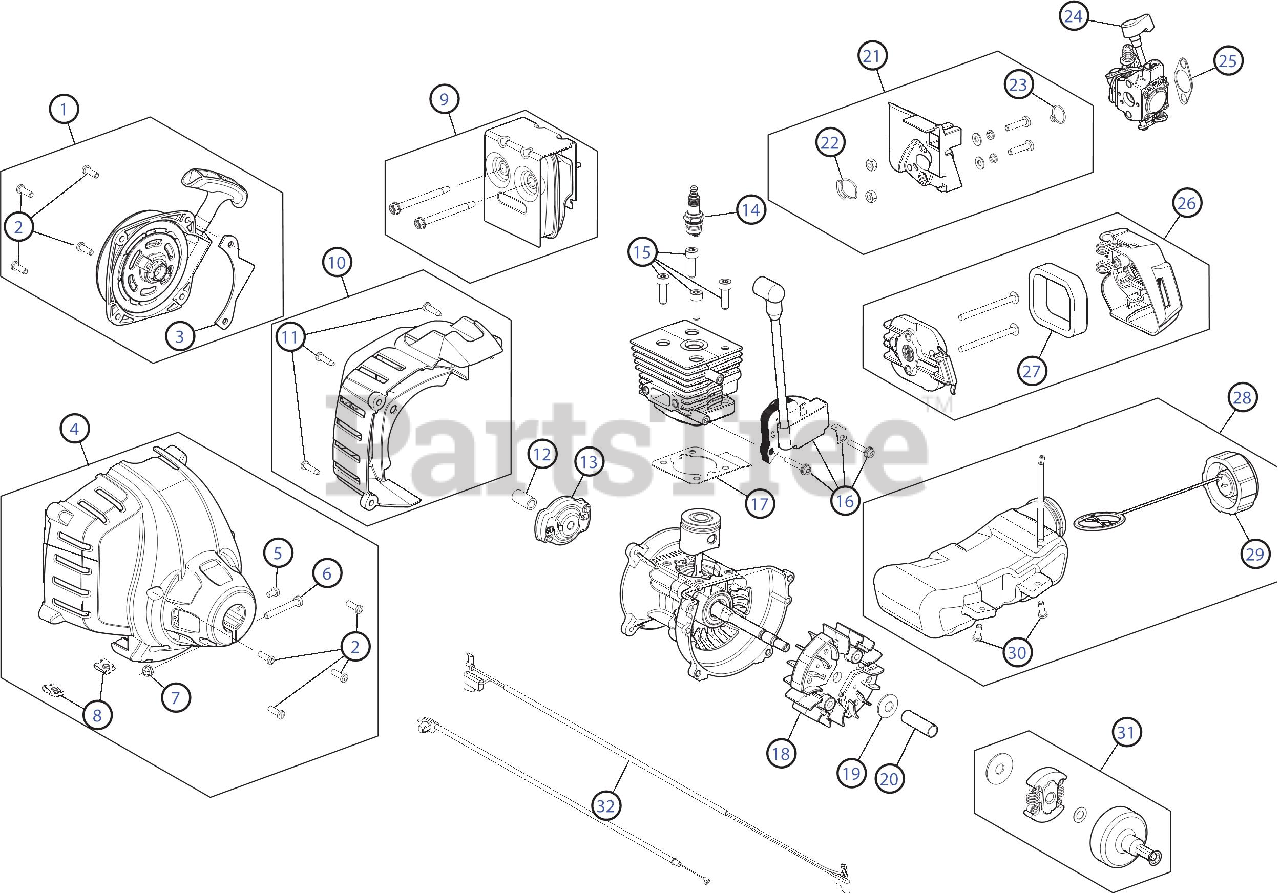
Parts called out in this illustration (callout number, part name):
1	Starter Assembly
2	Starter Screw
3	Starter Assembly Guard
4	Clutch Cover Assembly
5	Anti-Rotation Screw
6	Clamp Screw
7	Clamp Nut
8	U-shaped Nut
9	Muffler Assembly
10	Rear Engine Cover
11	Cover Screw
12	Adapter
13	Pawl Assembly
14	Spark Plug
15	Cylinder Bolt
16	Module Assembly
17	Cylinder Gasket
18	Flywheel Assembly
19	Washer
20	Spacer
21	Insulator Assembly
22	Insulator O-Ring
23	Carburetor O-Ring
24	Carburetor
25	Carburetor Gasket
26	Air Cleaner Assembly
27	Air Cleaner Filter
28	Fuel Tank Assembly
29	Fuel Tank Cap
30	Fuel Tank Screw
31	Clutch Assembly
32	Lead Wires
